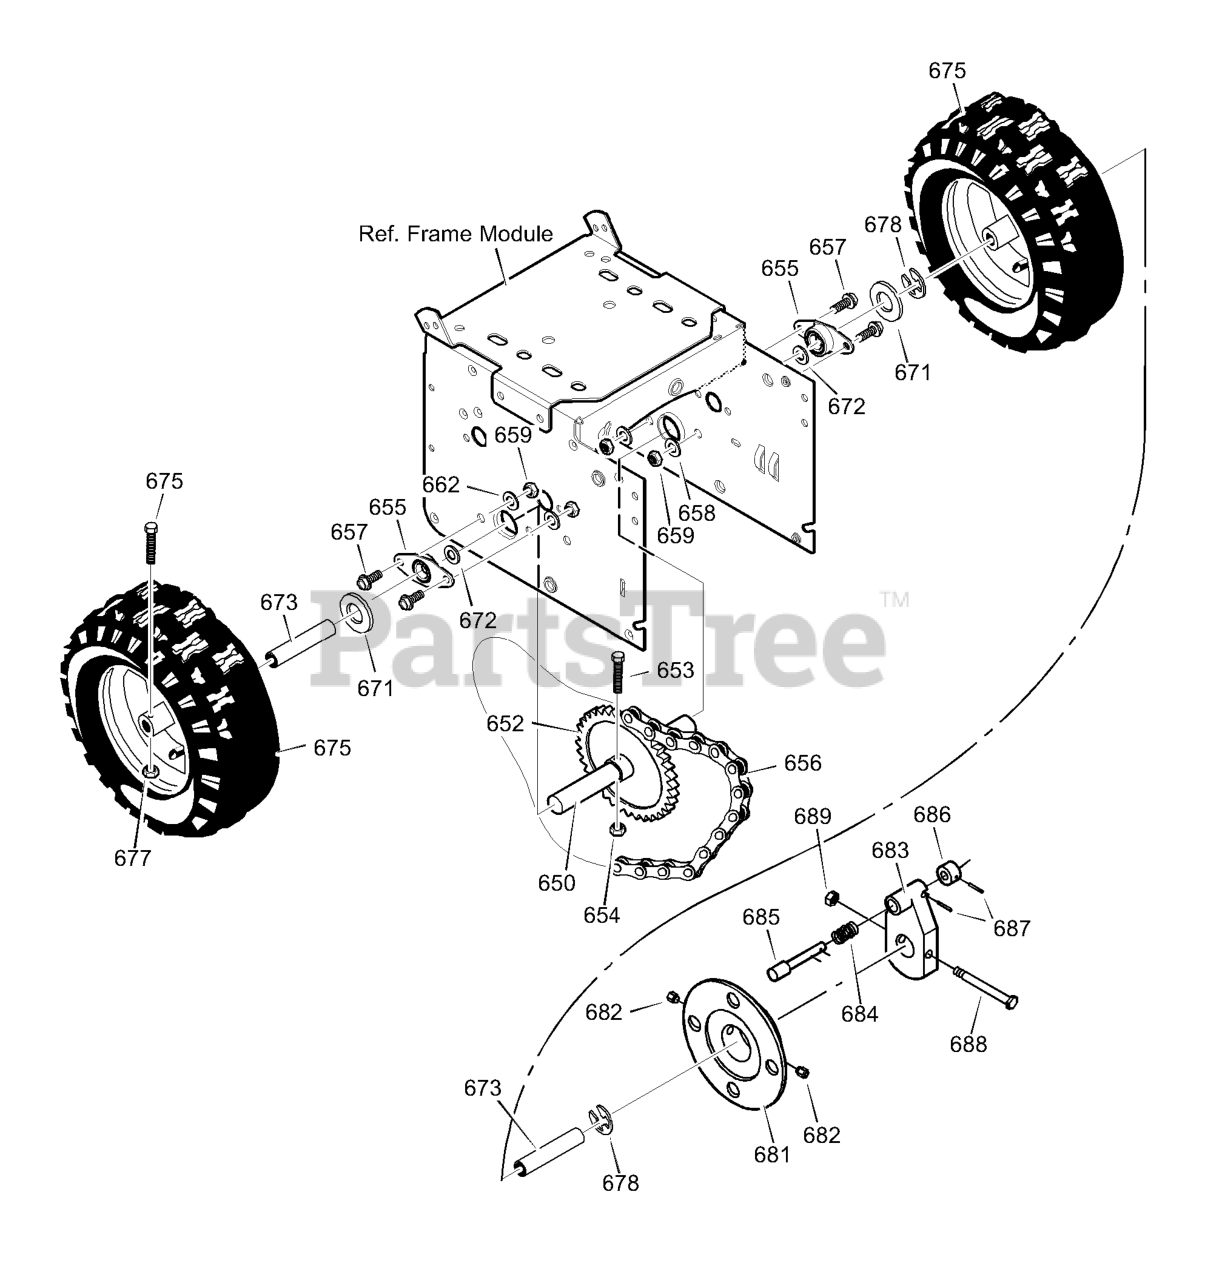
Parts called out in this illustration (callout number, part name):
650	AXLE BEARING ASSEMBLY
652	SPRKT & HUB
653	SCREW, 1/4-20X1.75
654	NUT, 1/4-20 HEX NYLOCK
655	RETAINER & BEARING ASSY
657	SCREW, 3/8"-16x.75
658	WASHER, LOCK
659	NUT, 3/8"-16
671	WASHER, FLAT
673	BUSHING, WHEEL
675	TIRE & RIM -RIGHT
676	SCREW, 1/4-20X1.75 HH
677	NUT, 1/4-20 HEX NYLOCK
678	RING, RET
680	TIRE & RIM -LEFT
681	DISC, WHEEL
682	SCREW, 3/8 x .50
683	HUB, WHEEL LOCK
684	SPRING, COMPRESSION
685	PIN, LOCK
688	SCREW, 1/4-20 x 2.25
689	NUTT, 1/4-20 HEX NYLOCK
